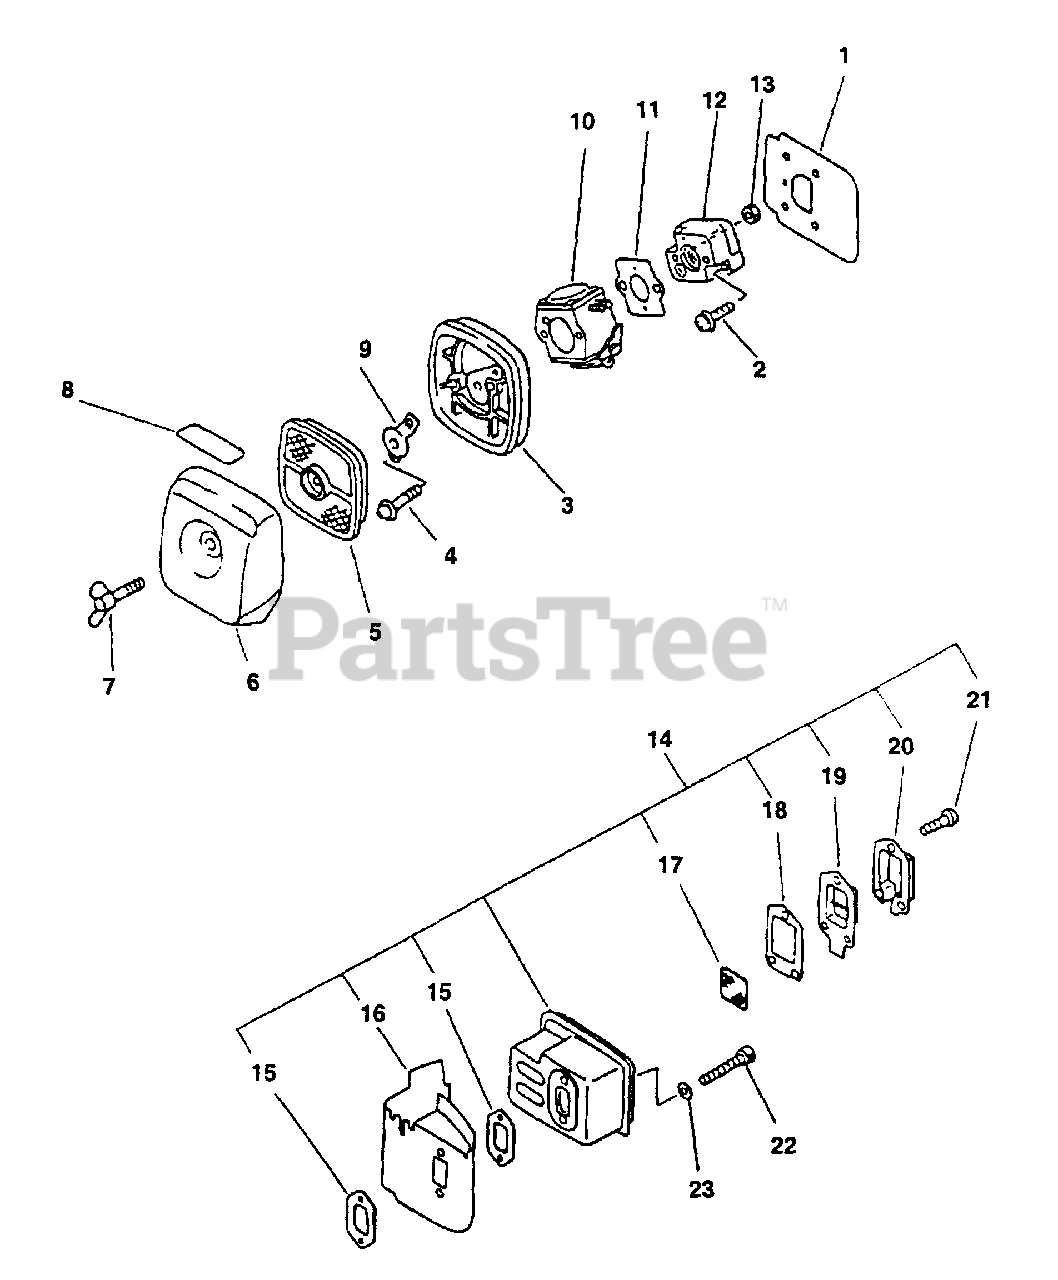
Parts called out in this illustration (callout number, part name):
1	SHIELD, INTAKE
2	SCREW - 5X20
3	AIR FILTER CASE ASSY
4	SCREW - 5X65
5	FILTER, AIR - SINGLE LAYER
6	COVER, AIR FILTER - GRAY
7	THUMBSCREW
8	LABEL - CHOKE
9	PLATE, PREVENT
10	CARBURETOR C1U-K47
10	CARBURETOR C1U-K52
11	GASKET, INTAKE
12	INSULATOR, INTAKE
14	MUFFLER ASSY
15	GASKET, EXHAUST
16	COVER, EXHAUST
17	SCREEN, SPARK ARRESTOR
18	GASKET, EXHAUST
19	GASKET, EXHAUST - INNER
20	GUIDE, EXHAUST - OUTER
21	SCREW - 4X10
22	SCREW - 5X55
23	WASHER - 5
